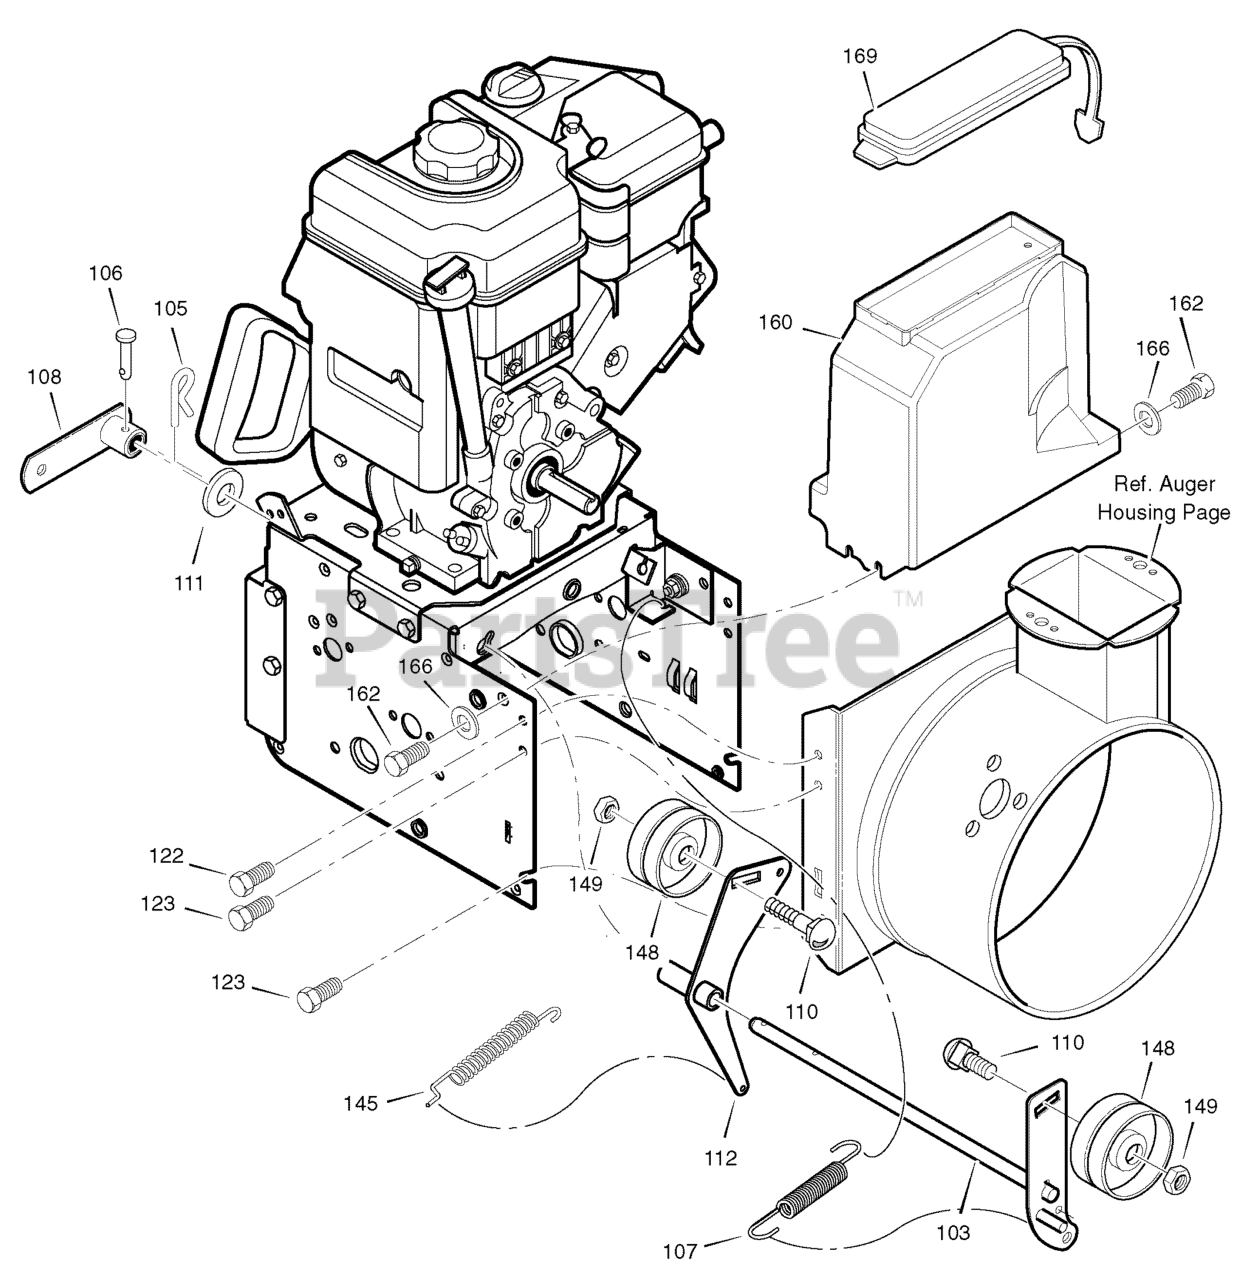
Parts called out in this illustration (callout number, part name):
103	IDLER ASSEMBLY, AUGER
105	PIN, HAIR .38DIAX1.64LG
106	PIN, CLEVIS 3/16" DIA
107	SPRING, TENSION
108	ASSY., SPRING ATTACH
110	BOLT, 3/8--16X1.25 CARR.
111	WASHER, FLAT
112	BRACKET, IDLER
122	SCREW, TAP 5/16--18 X .50
123	SCREW, TAP 5/16--18 X .75
145	SPRING, CLUTCH
148	PULLEY, IDLER
149	NUT, JAM 3/8--16
160	COVER, BELT
162	SCREW, TAP
166	WASHER, FLAT
169	LID, TOOL BOX
